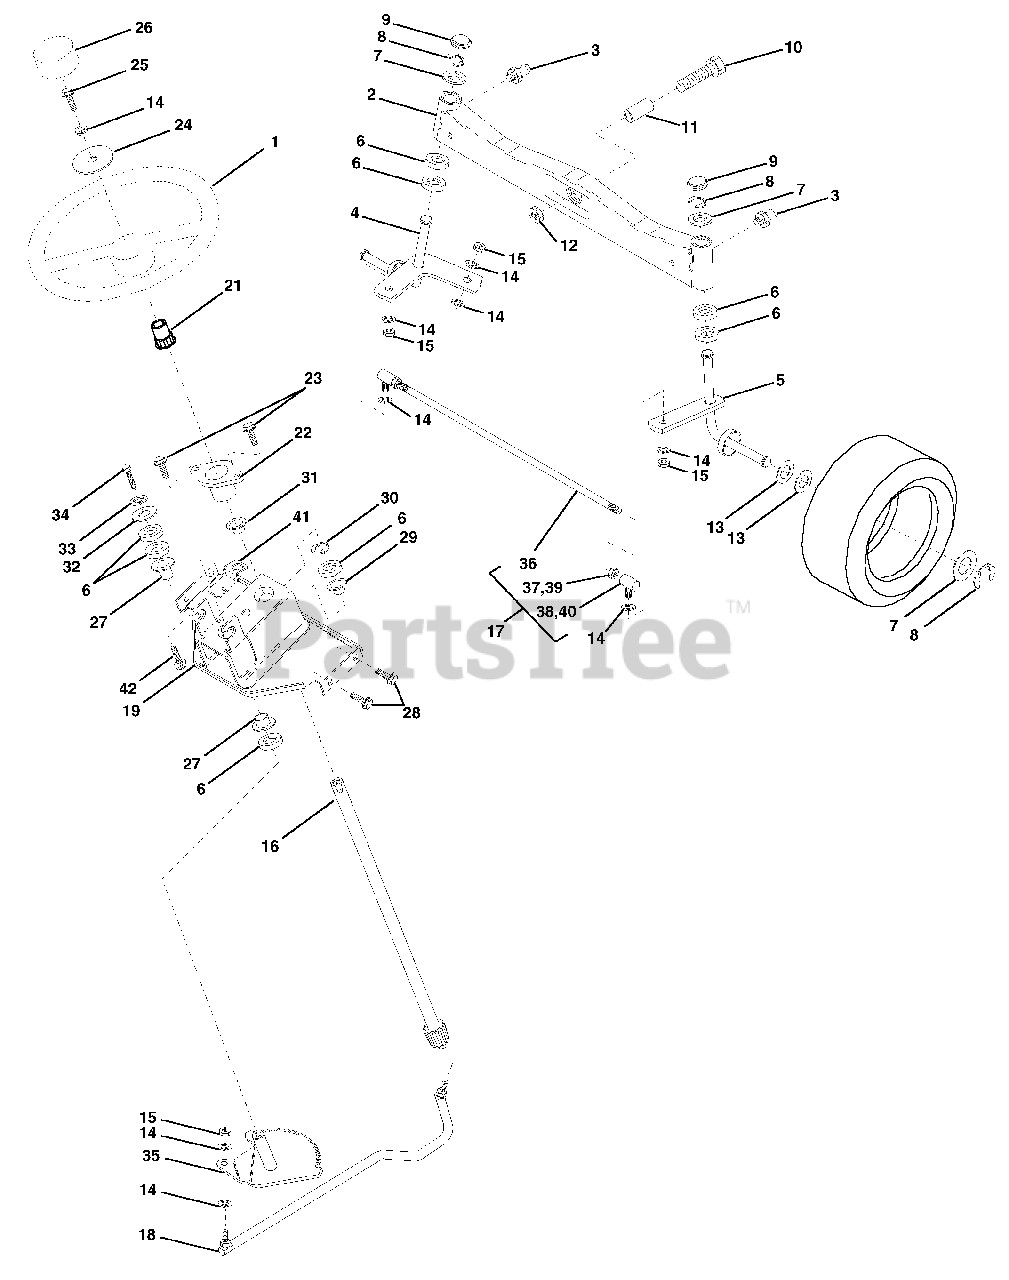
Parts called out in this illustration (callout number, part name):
1	Wheel, Steering
2	Axle Asm., Front
3	Fitting, Grease
4	Spindle Asm, LH
5	Spindle Asm., RH
6	Bearing, Race Thrust Harden
7	Washer 25/32 x 1-5/8 x 16 Ga.
8	Ring, Klip #T5304-75
9	Cap, Spindle
10	Bolt, Fin Hex 5/8-11 x 2-3/4
11	Spacer, Brg. Axle Front
12	Nut, Lock Flange 5/8-11 Unc
13	Washer 25/32 x 1-1/4 x 16 Ga.
14	Washer, Lock Hvy Hlcl Spr 3/8
15	Nut, Lock Center 3/8-24 Unf
16	Shaft Asm., Steering
17	Rod Asm., Tie Ball J Ball Vgt
18	Draglink, Ball Joint Solid Vgt
19	Support Asm., Steering Vgt
21	Adapter, Wheel Steering
22	Bushing, Strg.
24	Washer 13/32 x 1-1/20 x 11 Ga.
25	Bolt, Fin Hex 3/8-16 x 1 Gr. 5
26	Cap , Wheel Steering
27	Bearing, Col. Strg.
28	Screw Thdrol 3/8-16 x 3/4
29	Bearing, Flange
30	Ring, Klip Truarc #5304-75
31	Bushing, Nyliner Snap
32	Washer 11/32 x 1 x 10 Ga.
33	Washer, Lock Hvy Hlcl Spr 5/16
34	Bolt, Hex Hd 5/16-18 x 3/4
35	Gear, Sector Steering
36	Tie Rod
37	Jam Nut RH Thread
38	Joint Asm. Ball RH Thread
39	Jam Nut LH Thread
40	Joint Asm. Ball LH Thread
41	Bracket Switch Interlock
42	Screw Thdrol 5/16-18 x 1/2 Tyt
